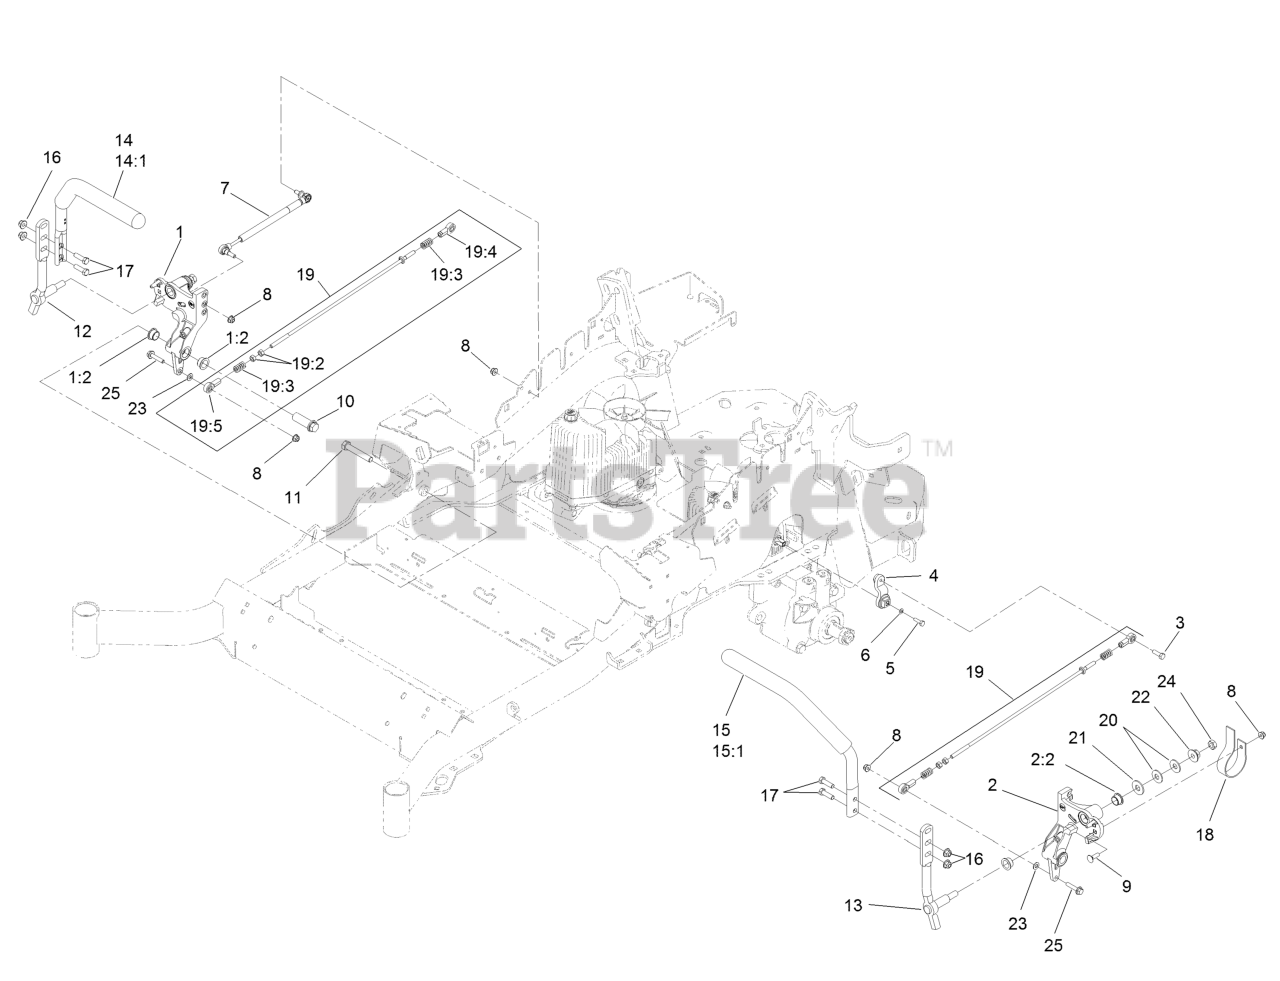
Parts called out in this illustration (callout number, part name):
1	RH Motion Control And Bushing ASM
1:2	Bushing-Flange
2	LH Motion Control And Bushing ASM
2:2	Bushing-Flange
3	Screw-HH, Thread Locking
4	Arm-Control, Pump
5	Screw-HH
6	Washer-Spring
7	Damper-Control, Motion
8	Nut-HF, NI
9	Bolt-CARR
10	Hub-Threaded
11	Screw-HH
12	Lever-Control Motion, RH
13	Lever-Control Motion, LH
14	RH Steering Handle ASM
14:1	Grip-Control, Lever
15	LH Steering Handle ASM
15:1	Grip-Control, Lever
16	Nut-HF, NI
17	Screw-HH
18	Spring-Leaf
19	Front Pump Linkage ASM
19:2	Nut-Hex
19:3	Spring-Compression
19:4	Balljoint-LH
19:5	Balljoint-RH
20	Washer-Spring
21	Washer-Flat
23	Washer-Plain
24	Nut-Jam
25	Screw-HHF
